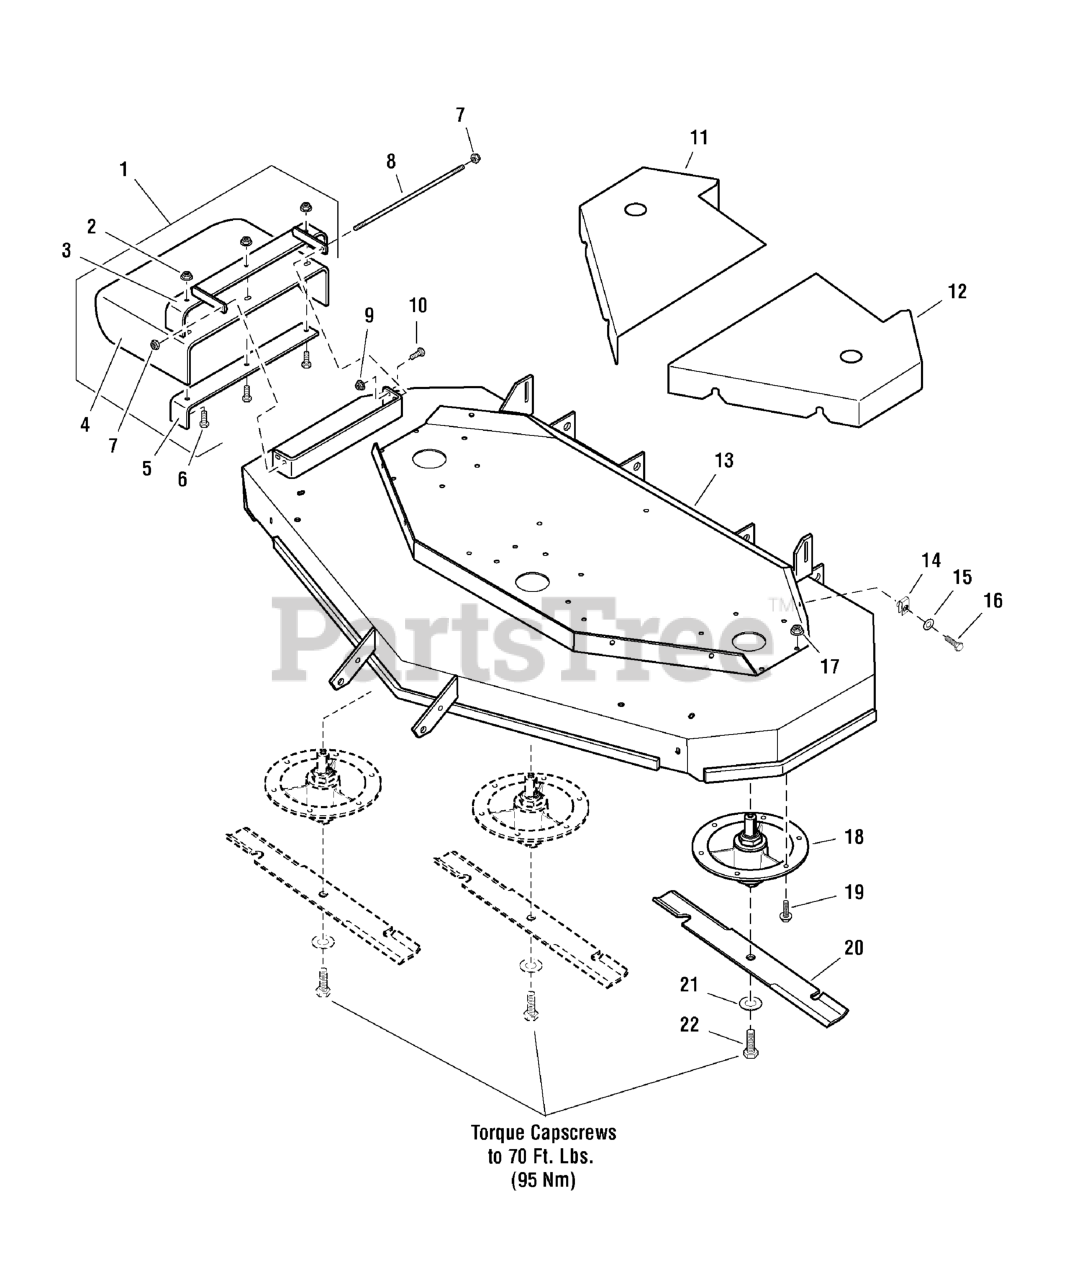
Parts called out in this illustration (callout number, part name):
1	61" RUBBER CHUTE ASSEMBLY, Complete
2	NUT, 3/8-16 Hex Nylock Flange
3	CHUTE FRAME
4	RUBBER CHUTE
5	CHUTE SUPPORT
6	BOLT, 3/8-16 X 1-1/4" GD5 CZ
7	NUT, 5/16-24 HEX NYLON LOCK
8	CHUTE MOUNT ROD
9	NUT, 5/16-18 Hex Nylock Flange
10	BOLT, 5/16-18 X 3/4 GD5
11	SPINDLE COVER - RH
12	SPINDLE COVER - LH
13	DECK SHELL W/DECALS, 61", IS3100Z
14	BODY CLIP, 5/16-18-7GA MATERIAL
15	WASHER, 5/16" SAE
16	BOLT, 5/16-18 X 3/4 GD5
17	NUT, 3/8-16 Hex Nylock Flange
18	SPINDLE ASSEMBLY
19	BOLT, Flange Head, 3/8-16 x 1-1/4
20	MOWER BLADE, 21"
21	WASHER, 5/8" GRADE 8, YZ
22	BOLT, 5/8-11 X 1-3/4 GD8
